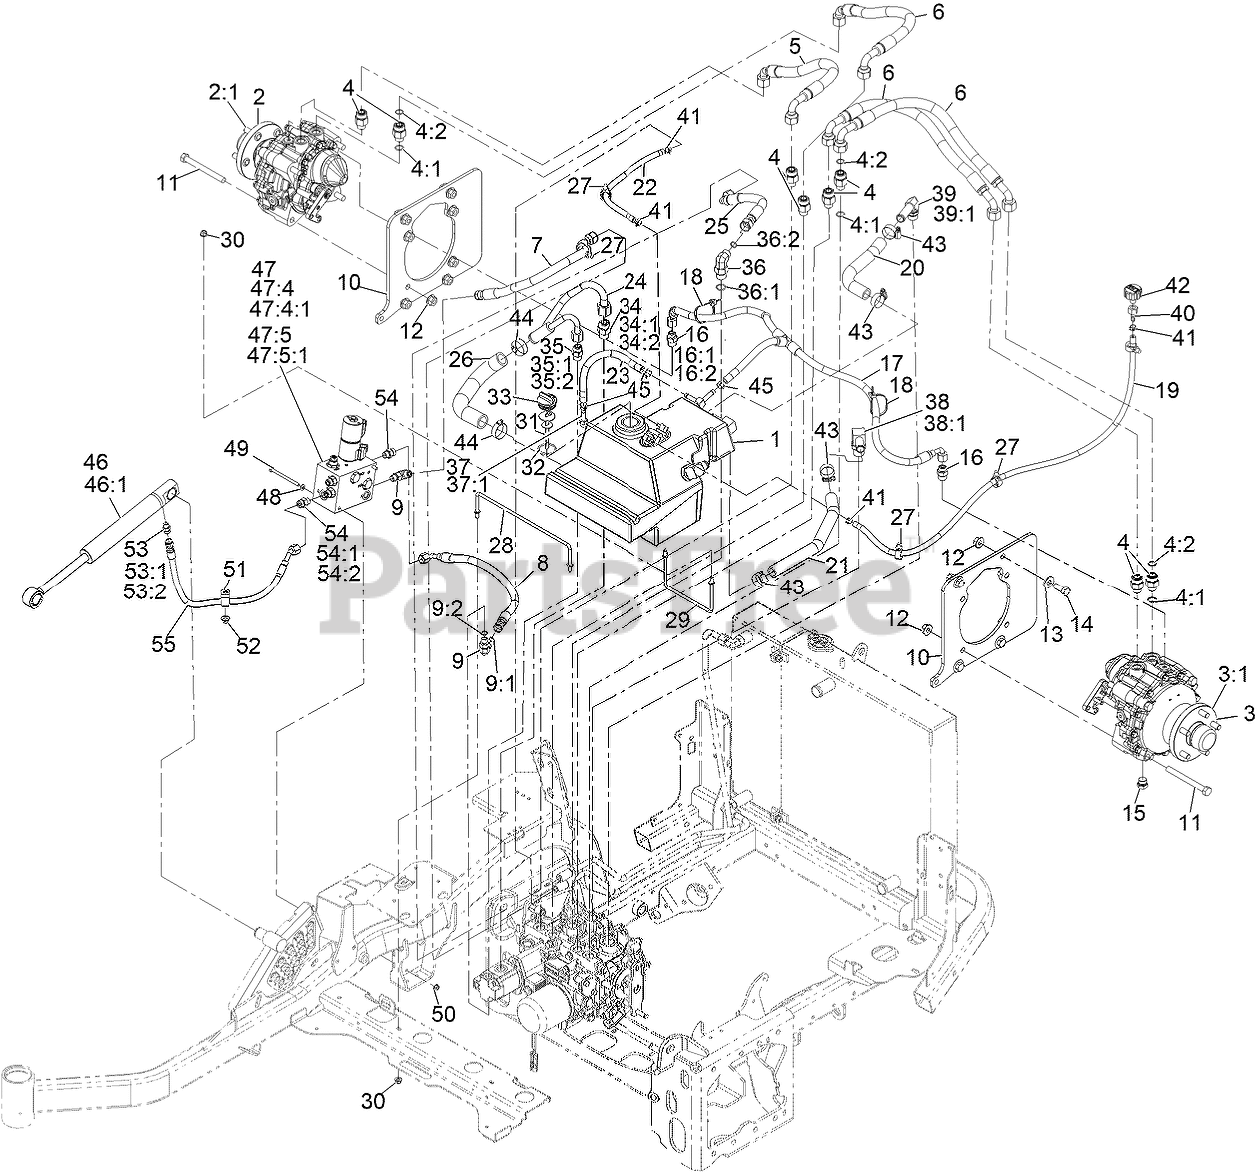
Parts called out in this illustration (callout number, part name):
1	HYD RESERVOIR ASM
2	MOTOR-HYD, RH
2:1	5 STUD WHEEL HUB KIT
3	MOTOR-HYD, LH
3:1	5 STUD WHEEL HUB KIT
4	FITTING-STRAIGHT
4:1	O-RING
5	HOSE ASM
6	HOSE ASM
7	HOSE ASM
8	HOSE ASM
9	FITTING-ELBOW, 90 DEG
9:1	O-RING
9:2	O-RING
10	PLATE-MOTOR
11	SCREW-HH
12	NUT-HHF
13	WASHER-SPRING
14	SCREW-HH
15	PLUG-MAGNETIC
16	FITTING-STRAIGHT
16:1	O-RING
16:2	O-RING
17	TEE HOSE ASM
18	TIE-CABLE
20	HOSE-RETURN
21	HOSE-RETURN
24	TUBE ASM
25	HOSE ASM
26	HOSE-SUCTION
27	CLIP-TIE
28	ROD-SUPPORT, HYD TANK
29	ROD-SUPPORT, HYD TANK
30	NUT-HF, NI
31	DIPSTICK
33	PLUG-PLASTIC
34	FITTING-STRAIGHT
34:1	O-RING
34:2	O-RING
35	FITTING-STRAIGHT
35:1	O-RING
35:2	O-RING
36	FITTING-ELBOW, 90 DEG
36:1	O-RING
36:2	O-RING
37	ADAPTER-STRAIGHT
37:1	O-RING
38	FITTING-ELBOW, 90
38:1	O-RING
39	FITTING-90
39:1	O-RING
40	FITTING-STRAIGHT
41	CLAMP-HOSE
42	BREATHER
43	CLAMP-HOSE
44	CLAMP-HOSE
45	CLAMP-HOSE
46	CYLINDER-LIFT
47	Valve-Lift And Hold
47:4	SOLENOID VALVE ASM
47:4:1	SPOOL VALVE SEAL KIT
47:5	VALVE-COUNTERBALANCE
47:5:1	Seal Kit
48	WASHER-FLAT
49	SCREW-HH
51	CLIP-LOOM
52	NUT-HF, NI
53	FITTING-HYD, STRAIGHT
53:1	O-RING
53:2	O-RING
54	FITTING-STRAIGHT
54:1	O-RING
54:2	O-RING
55	HOSE ASM
